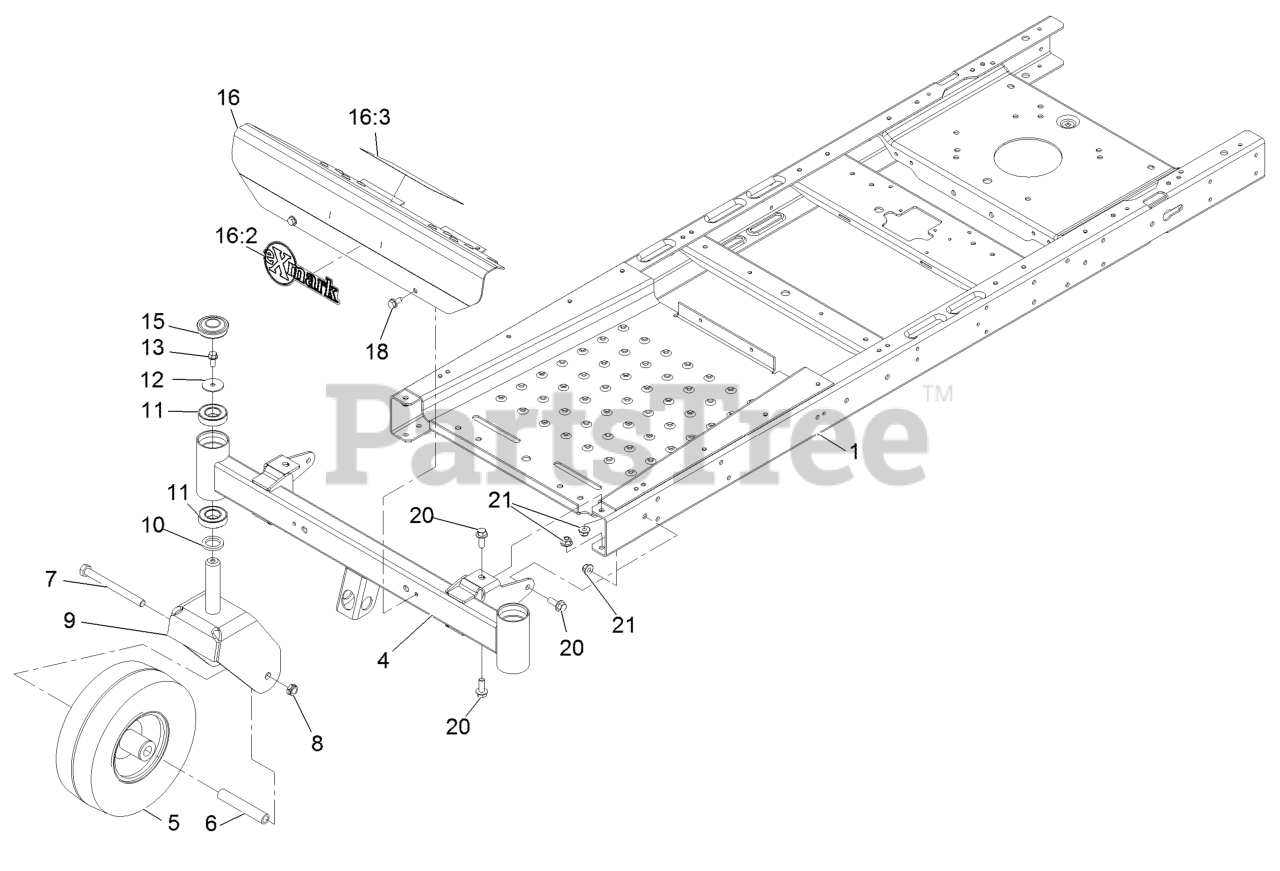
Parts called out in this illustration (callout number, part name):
1	FRAME ASM
4	AXLE-FRONT, NARROW
5	CASTER WHEEL ASM
6	BUSHING-SPANNER
7	SCREW-HH
8	NUT-HEX
9	CASTER FORK ASM
10	WASHER-THRUST
11	BEARING-BALL
12	WASHER-FLAT
13	SCREW-HHF
15	CAP-GREASE
16	FOOTREST ASM
16:2	DECAL-EXMARK LOGO
16:3	DECAL-DANGER
18	Screw-HWH 5/16-18 X 3/4 Tf
20	SCREW-HHF 3/8-16 X 1
21	NUT-HF, NI
